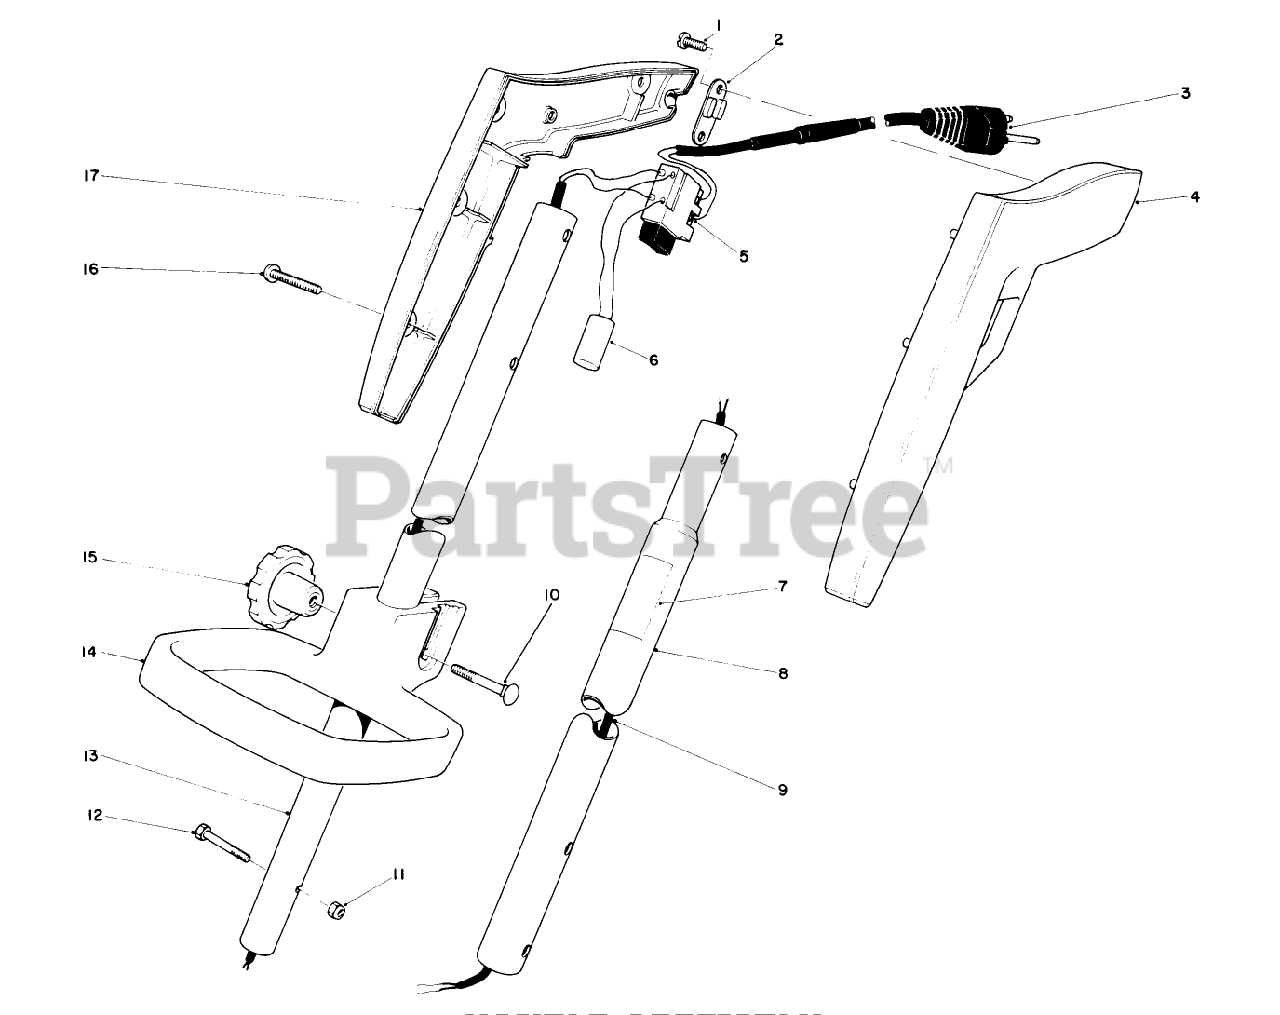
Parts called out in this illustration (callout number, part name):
1	SCREW-PPH
2	Clamp
3	Power Cord
4	Grip-Left Hand
5	Switch
6	Suppressor
7	Caution Decal
8	Tube-Lower
9	Wiring Harness
10	BOLT-CARR
11	NUT-LOCK, NI
12	HEX HD MACHINE SCREW
13	Tube-Upper
14	ADJUSTABLE HANDLE
17	Grip-Right Hand
